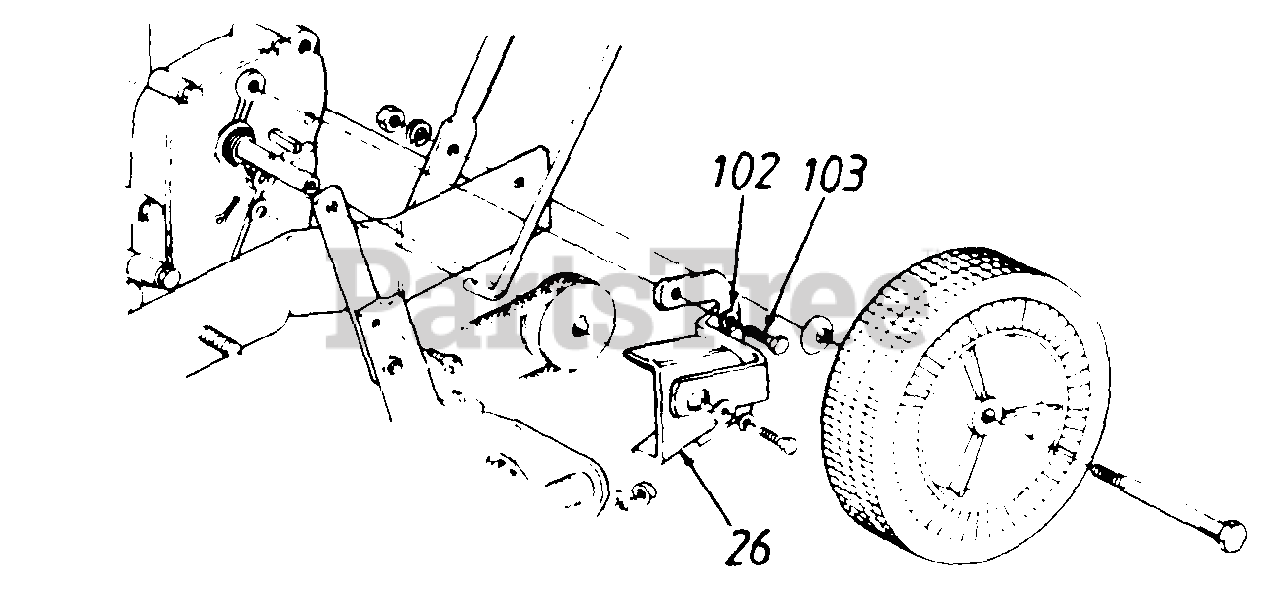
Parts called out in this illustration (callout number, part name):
20	Engine Pulley
26	Belt Guard Ass'y
31	Spring Pin Spir. 1/4"
102	L-Wash. 5/16 I.D.
103	Hex Screw 5/16-24 x .5"
